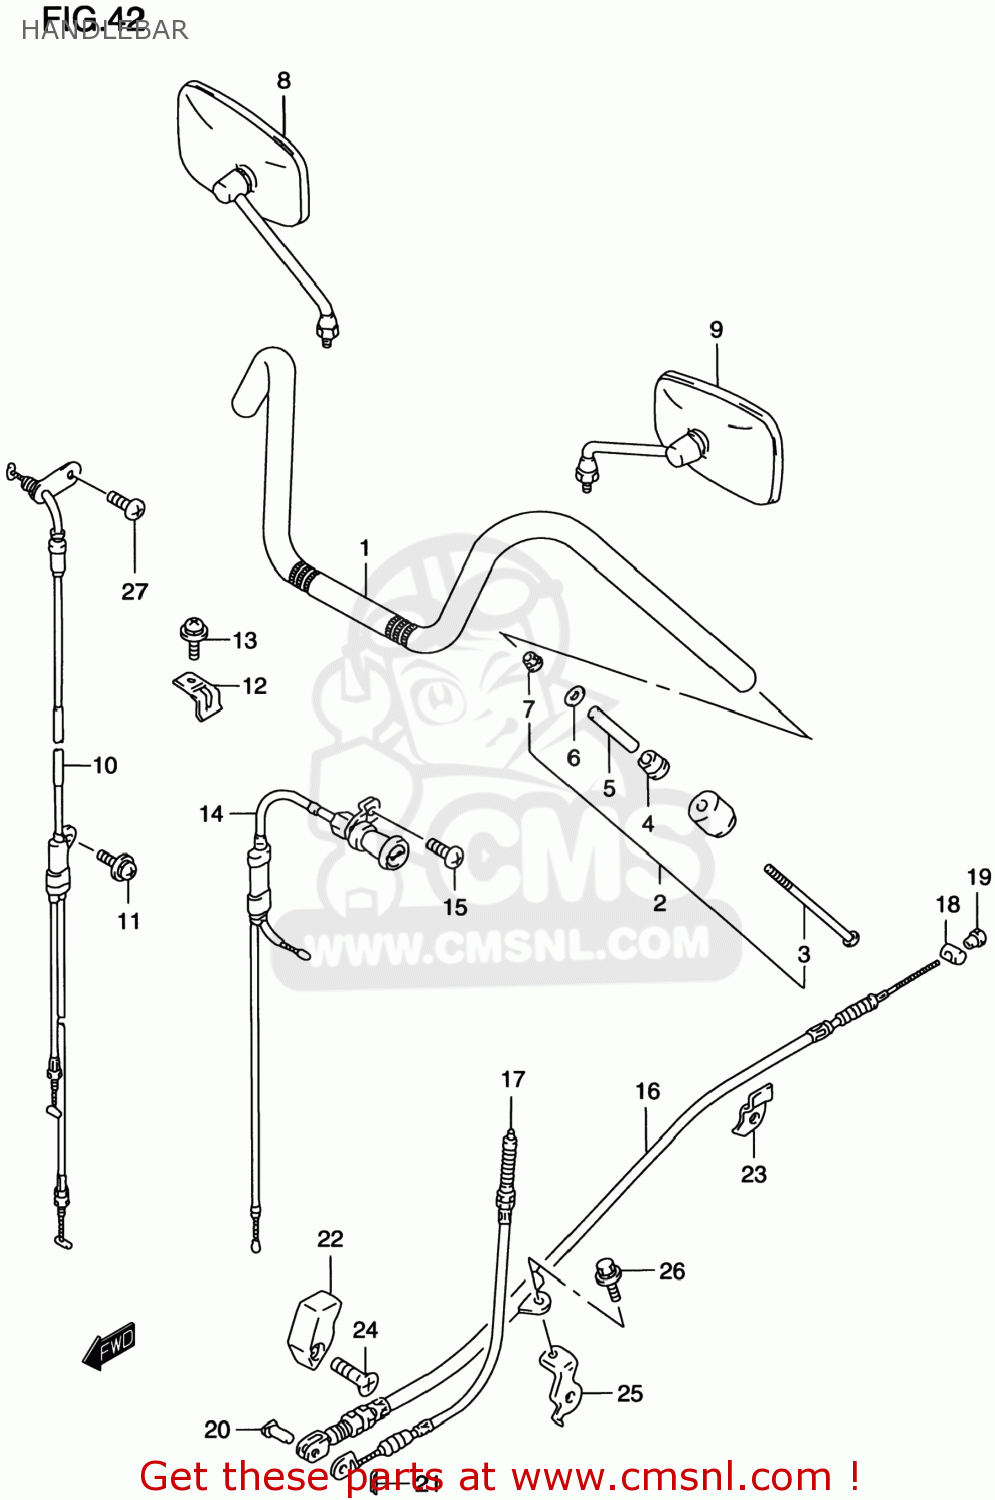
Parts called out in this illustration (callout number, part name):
1	HANDLEBAR
2	BALANCER SET,HANDLEBAR
3	SCREW(6X110)
4	EXPANDER,HANDLE BALANCER NO.2
5	SPACER,EXPANDER
6	WASHER(6.5X18X2)
7	NUT
8	MIRROR ASSY,RR VIEW,R
9	MIRROR ASSY,RR VIEW,L
10	CABLE ASSY,THROTTLE
11	SCREW
12	CLAMP,THROTTLE CABLE
13	SCREW
14	CABLE ASSY,STARTER
15	SCREW 6X10
16	CABLE,RR BRAKE
17	CABLE,STOP LAMP SWITCH
18	PIN(13X18)
19	NUT
20	PIN(L:17.5)
21	PIN
22	GUIDE,RR BRAKE CABLE
23	CLAMP,RR BRAKE CABLE
24	SCREW
25	BRACKET,RR BRAKE CABLE
26	BOLT
27	SCREW
